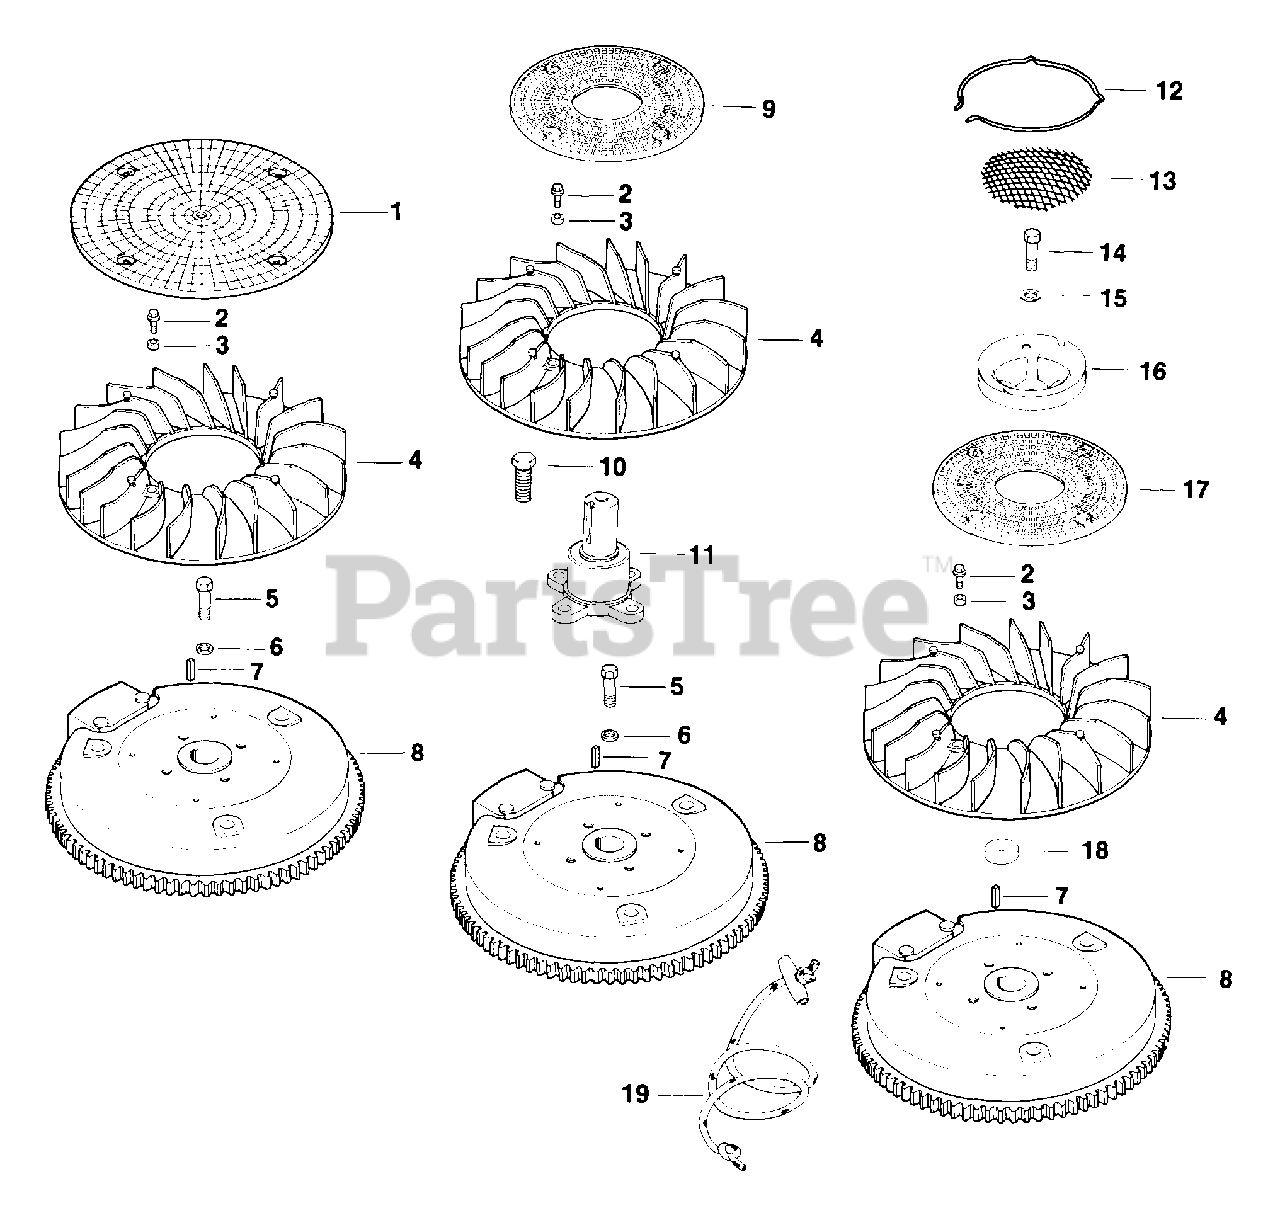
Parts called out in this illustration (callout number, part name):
1	SCREEN, GRASS
2	SCREW, WSH HD 1/4-20X5/8" - DISCONTINUED
5	SCREW, MACH 3/8-24X1-1/4"
6	WASHER (KM)-USE 12 468 03-S
8	FLYWHEEL - DISCONTINUED
